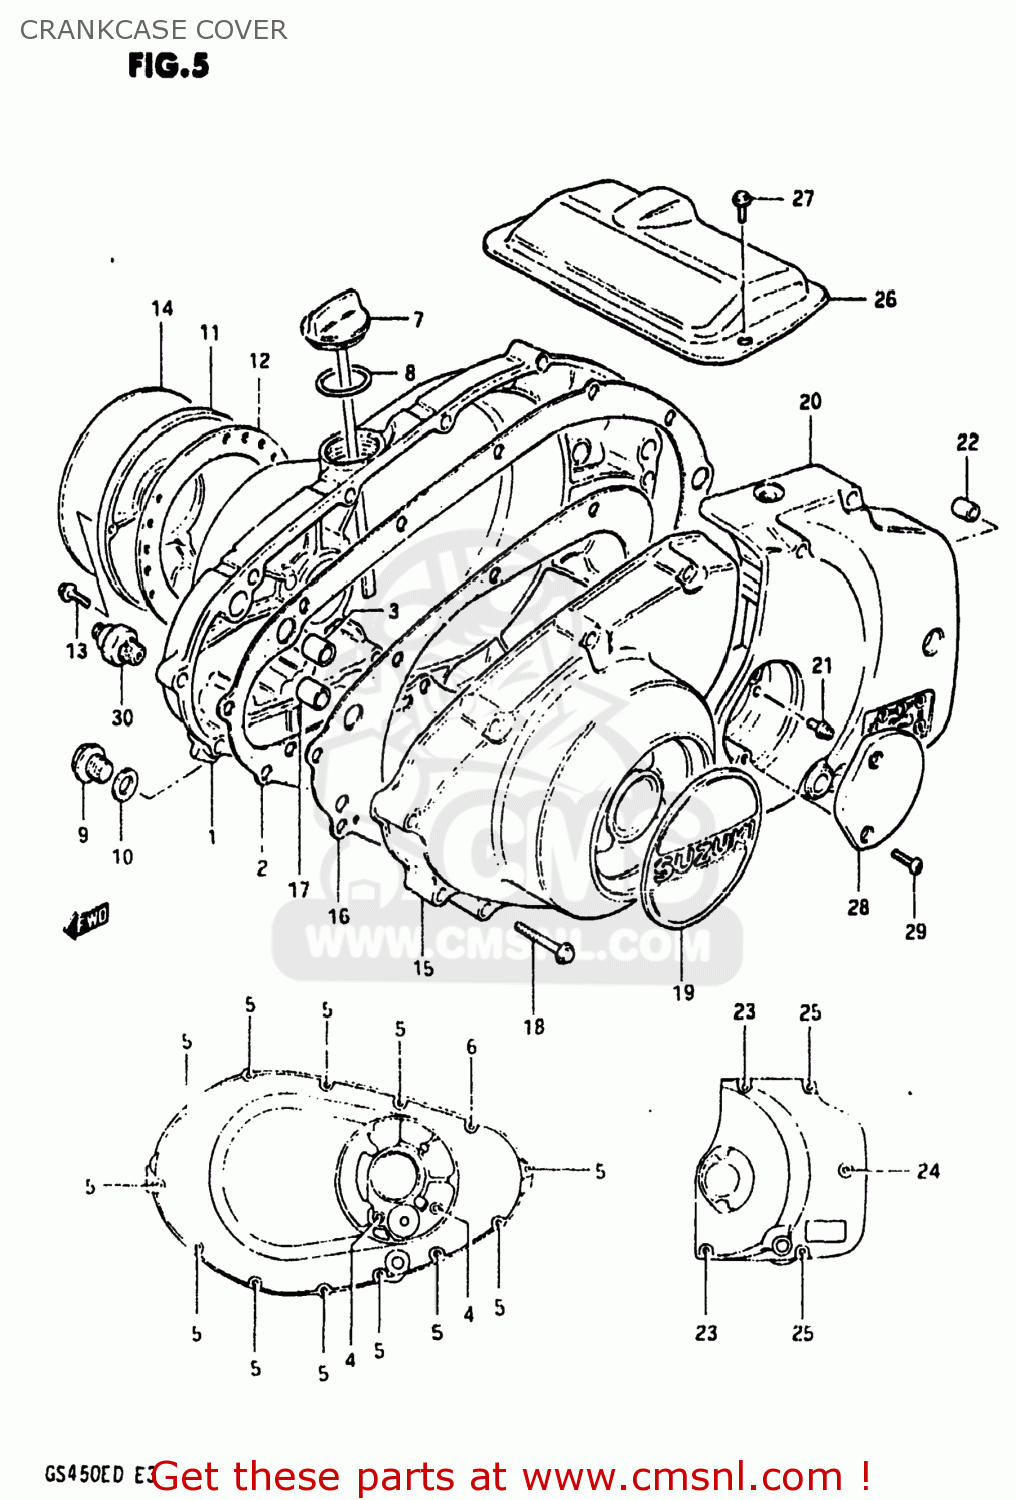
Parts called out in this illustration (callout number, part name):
1	COVER,CLUTCH
2	GASKET,CLUTCH COVER (MCA)
3	PIN
4	BOLT (6X55)
5	BOLT (6X35)
6	BOLT
7	GAUGE,OIL LEVEL
8	O-RING
9	PLUG (14X12)
10	GASKET(14X19.2X2) (NAS)
11	COVER,CONTACT BREAKER
12	GASKET,CONTACT BREAKER COVER (NAS)
13	BOLT 5X16
14	EMBLEM,MAGNETO COVER
15	COVER,MAGNETO
16	GASKET,MAGNETO COVER (MCA)
17	PIN
18	BOLT (6X35)
19	EMBLEM,MAGNETO COVER
20	COVER,ENGINE SPROCKET
21	NIPPLE
22	PIN
23	BOLT (6X65)
24	BOLT (6X50)
25	BOLT (6X40)
26	COVER,STARTER MOTOR
27	BOLT
28	CAP,CLUTCH RELEASE ADJUST
29	SCREW 5X12
30	SWITCH ASSEMBLY
